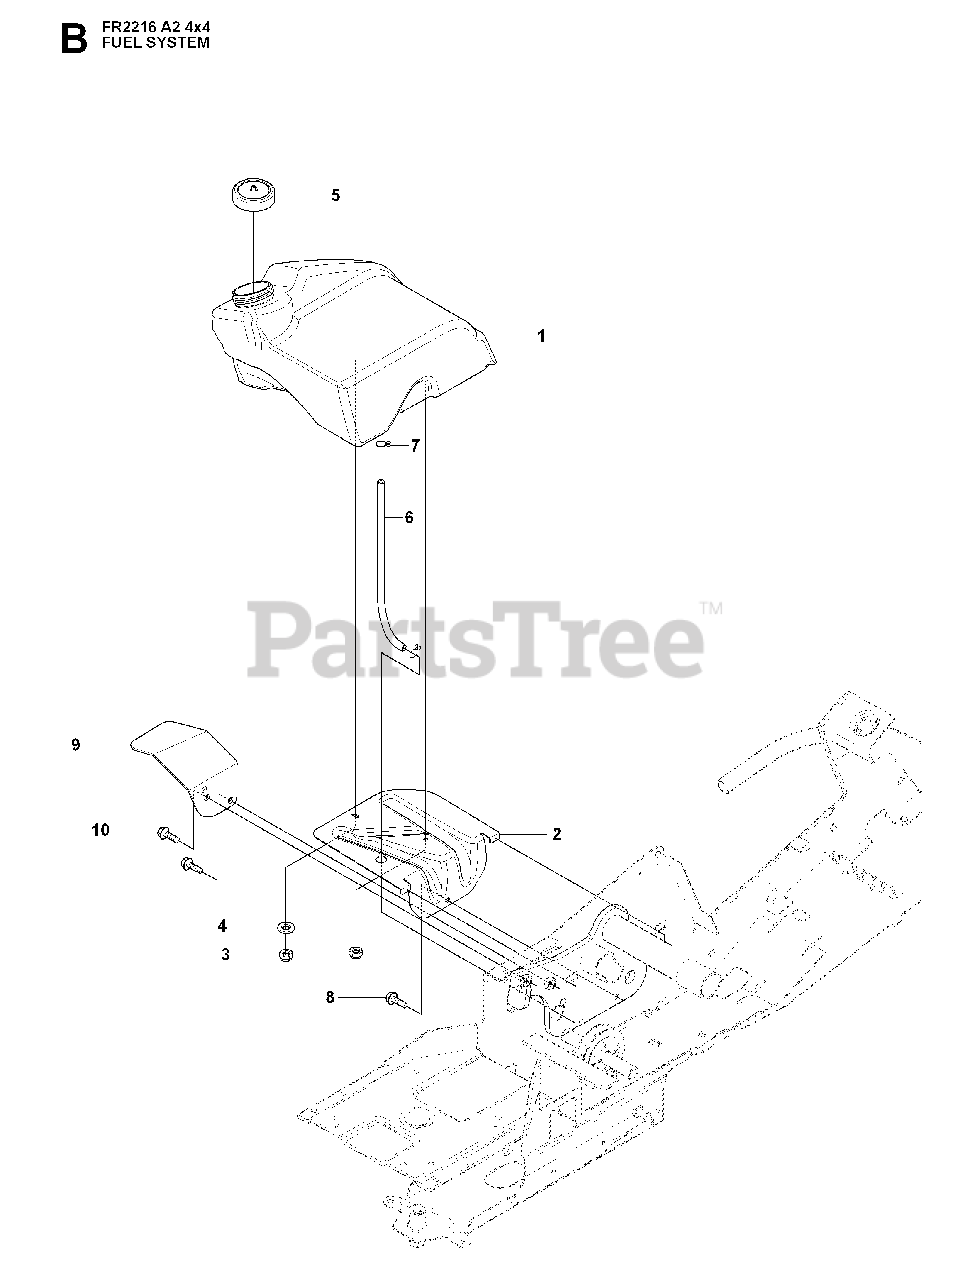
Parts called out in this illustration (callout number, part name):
3	LOCKNUT M6
4	WASHER
10	SCREW M10X25
